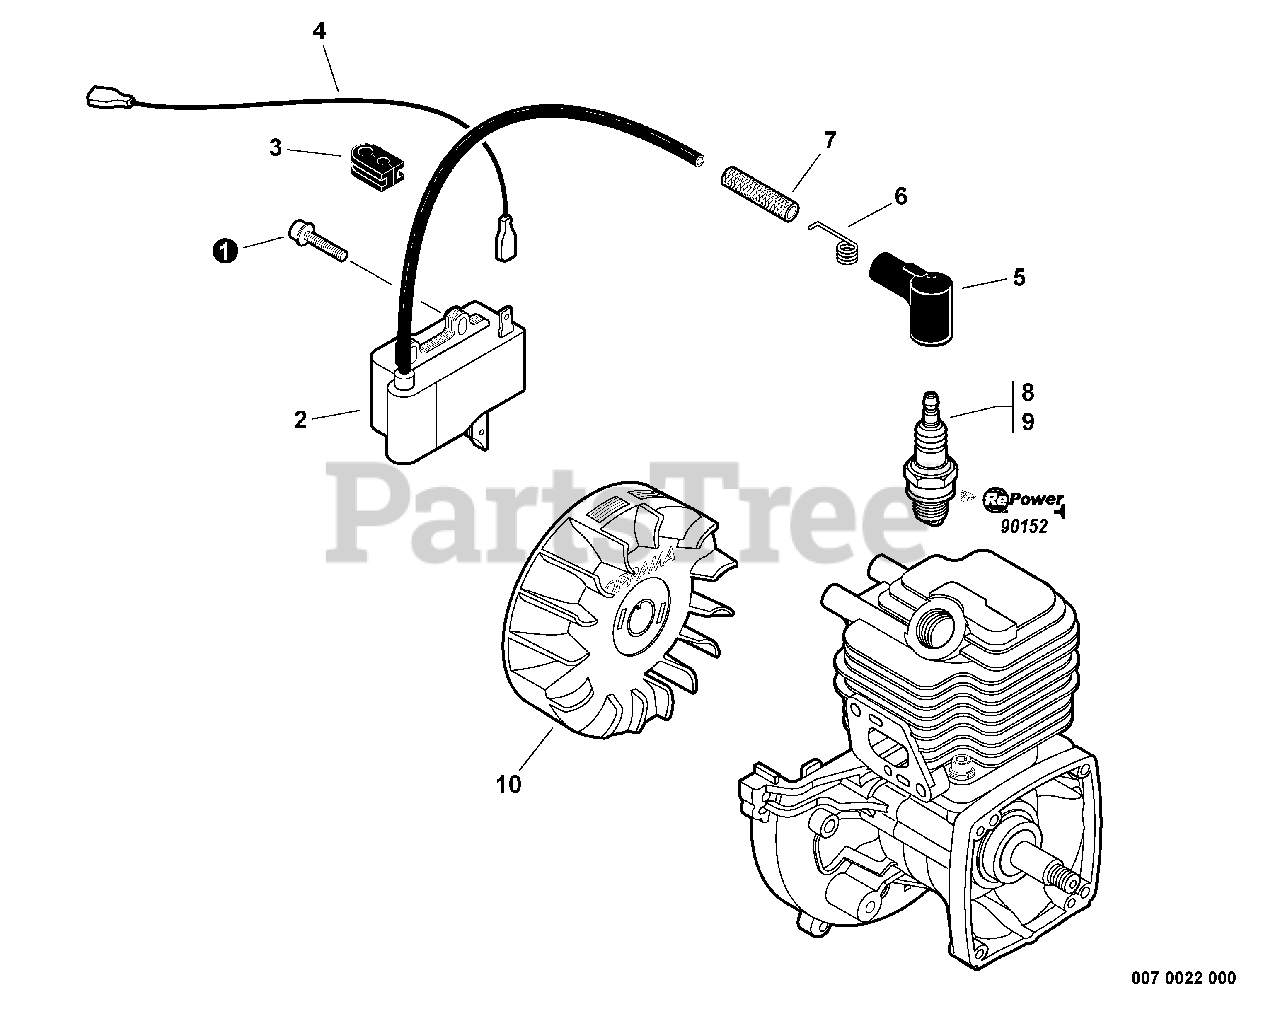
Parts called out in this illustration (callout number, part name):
1	BOLT 4×20
2	COIL, IGNITION
5	CAP, SPARK PLUG
6	TERMINAL, SPARK PLUG
7	TUBE, INSULATOR
8	SPARK PLUG - BPM8Y
9	SPARK PLUG - BPMR8Y
10	FLYWHEEL
11	TUNE-UP KIT - REPOWER
